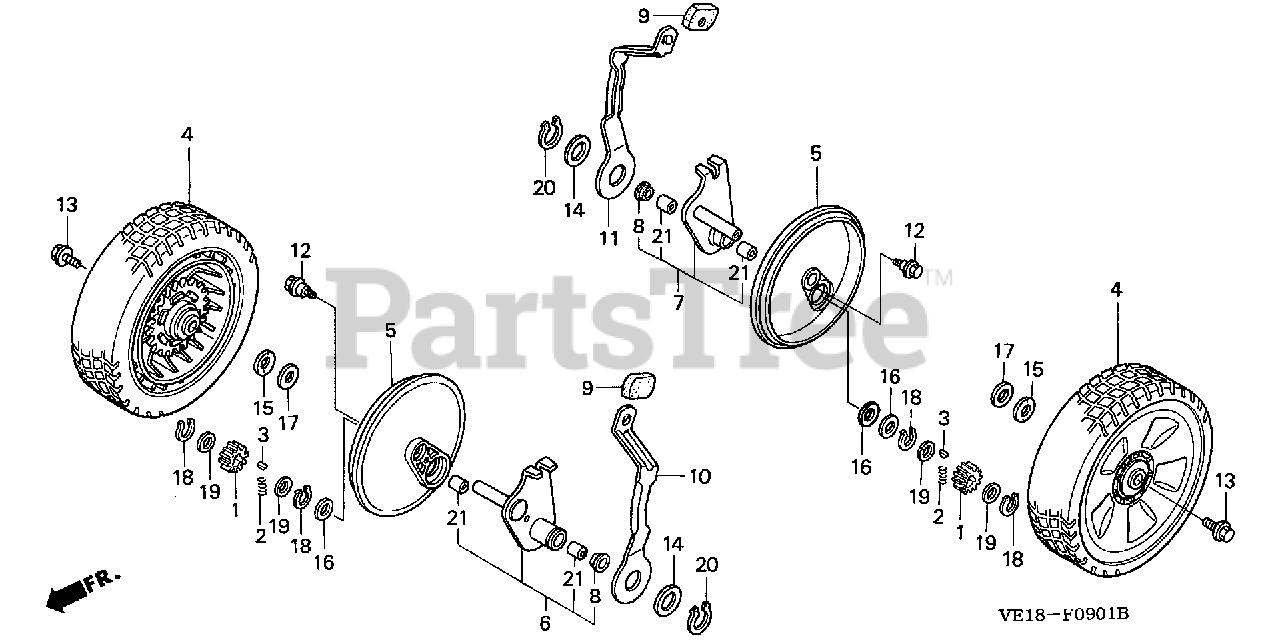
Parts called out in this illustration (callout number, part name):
1	GEAR, PINION (12T)
2	SPRING, RATCHET RETURN
3	KEY, RATCHET
4	WHEEL, RR. *NH31* (MCKINLEY WHITE)
6	ARM, R. RR. ADJUSTING
7	ARM, L. RR. ADJUSTING
8	DUST SEAL (12.7MM)
9	GRIP, ADJUSTER
10	PLATE, R. RR. ADJUSTER
11	PLATE, L. RR. ADJUSTER
12	SCREW, TAPPING (5X12)
13	BOLT, WHEEL
14	WASHER, PLAIN (22MM)
15	WASHER, WHEEL
16	WASHER, THRUST (13MM)
17	WASHER, THRUST (13X27X1)
18	CIRCLIP (OUTER) (12.7MM)
19	COLLAR, PINION GEAR
20	CIRCLIP (OUTER) (22MM)
21	BUSH, DRIVESHAFT
